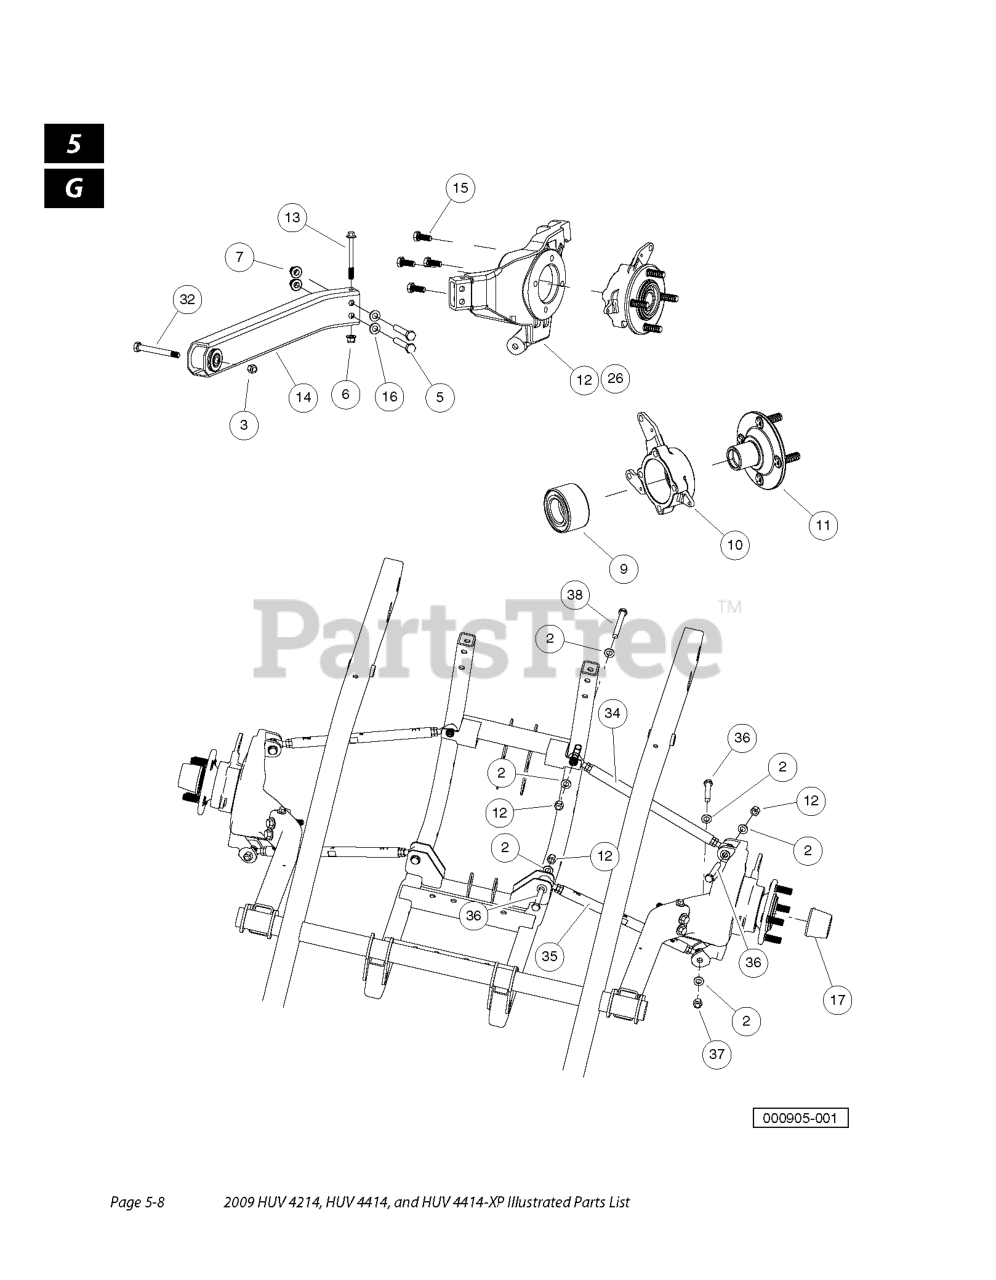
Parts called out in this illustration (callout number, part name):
2	WASHER, 3/8 FLAT
3	NUT FLG, M12X1.75, NYLON GR 10
5	SCREW M10-1.5X60MM HEX CAP
6	LOCK NUT, FLG M8 X 1.25 NYLON
7	NUT FLG M10 X 1.5 NYLON
9	BEARING, DAC
11	ASM, WHEEL HUB, REAR
12	ANCHOR, TRAILING ARM, RH
13	BOLT, FLG, M8 X 1.25 X 80
14	ASM, SWING, ARM
15	BOLT, M10 X 1.5 X 25
16	WASHER, M10 HARD
17	CAP, WHEEL, RUBBER
18	ASM, TRAILING ARM, LH
19	SCREW M10-1.5X60MM HEX CAP
20	LOCK NUT, FLG M8 X 1.25 NYLON
21	NUT FLG M10 X 1.5 NYLON
22	ASM, UPRIGHT, REARAR
23	BEARING, DAC
25	ASM, WHEEL HUB, REAR
26	ANCHOR, TRAILING ARM, LH
27	BOLT, FLG, M8 X 1.25 X 80
28	ASM, SWING, ARM
29	BOLT, M10 X 1.5 X 25
30	WASHER, M10 HARD
31	SLEEVE, LINK, SHORT
32	BOLT, FLG, M12 X 1.75 X 80
34	ASM, LAT-LINK REAR
36	SCREW, 3/8-16 X 2.25 HX HD CAP
37	LOCKNUT, 3/8-16 HEX
38	SCREW, 3/8-16 X 3.375
